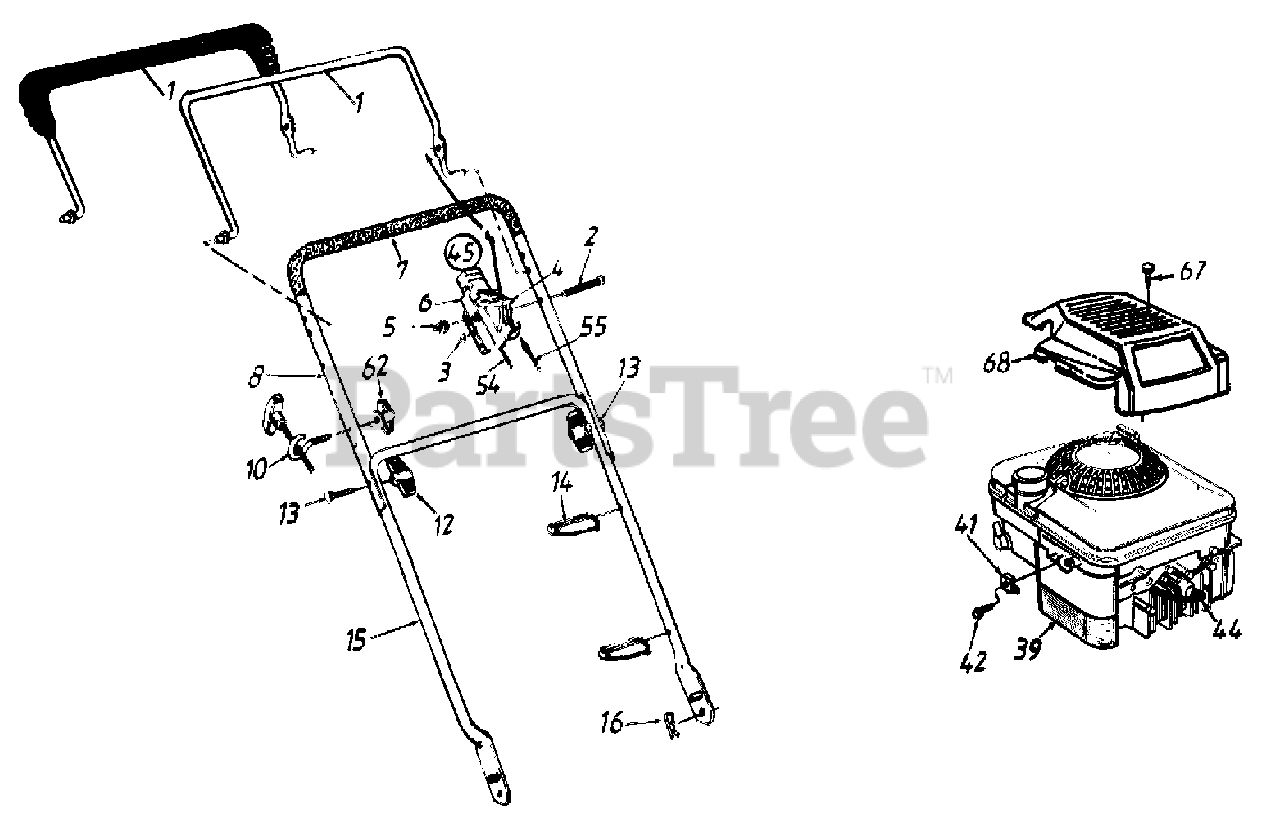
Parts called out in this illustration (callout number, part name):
1	Control Handle Ass'y.
2	Oval C-Sunk Screw
3	Spring Washer
4	Throttle Lever
5	Hex Lock Nut
6	Throttle Body
7	Foam Grip
8	Upper Handle
10	Rope Guide
12	Hand Knob
13	Carriage Bolt
14	Cable Tie
15	Lower Handle
16	Hairpin Clip
39	Engine
41	Cable Clamp
42	Hex TT Screw #10-32 x .62"
44	Spark Plug Boot
45	Throttle Box Comp.
54	Throttle Cable
55	Control Cable
62	Handle Knob
67	Hi-Lo Screw
68	Engine Shroud
